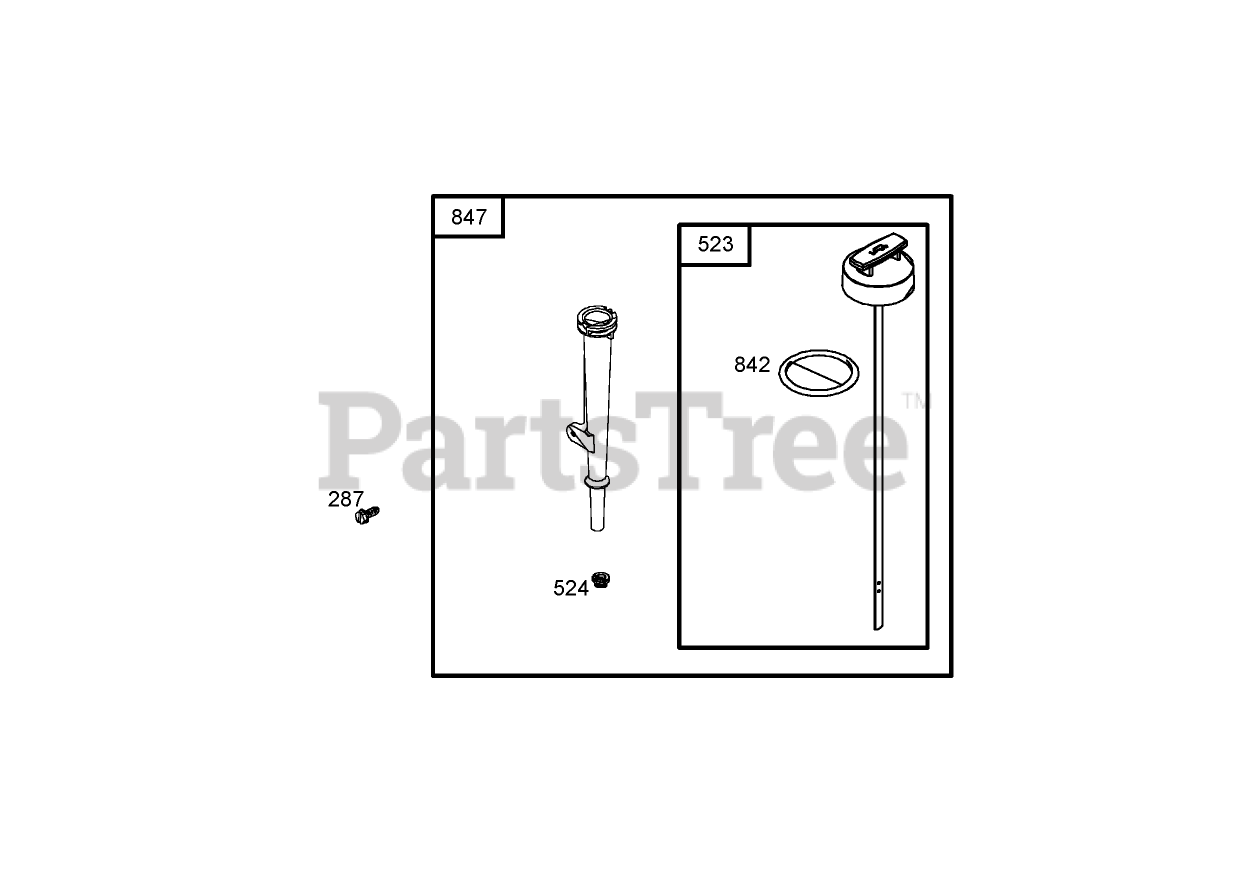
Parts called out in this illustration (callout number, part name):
287	Screw (Dipstick Tube)
523	Dipstick
524	Seal
842	Seal-O Ring
847	Dipstick and Tube ASM
